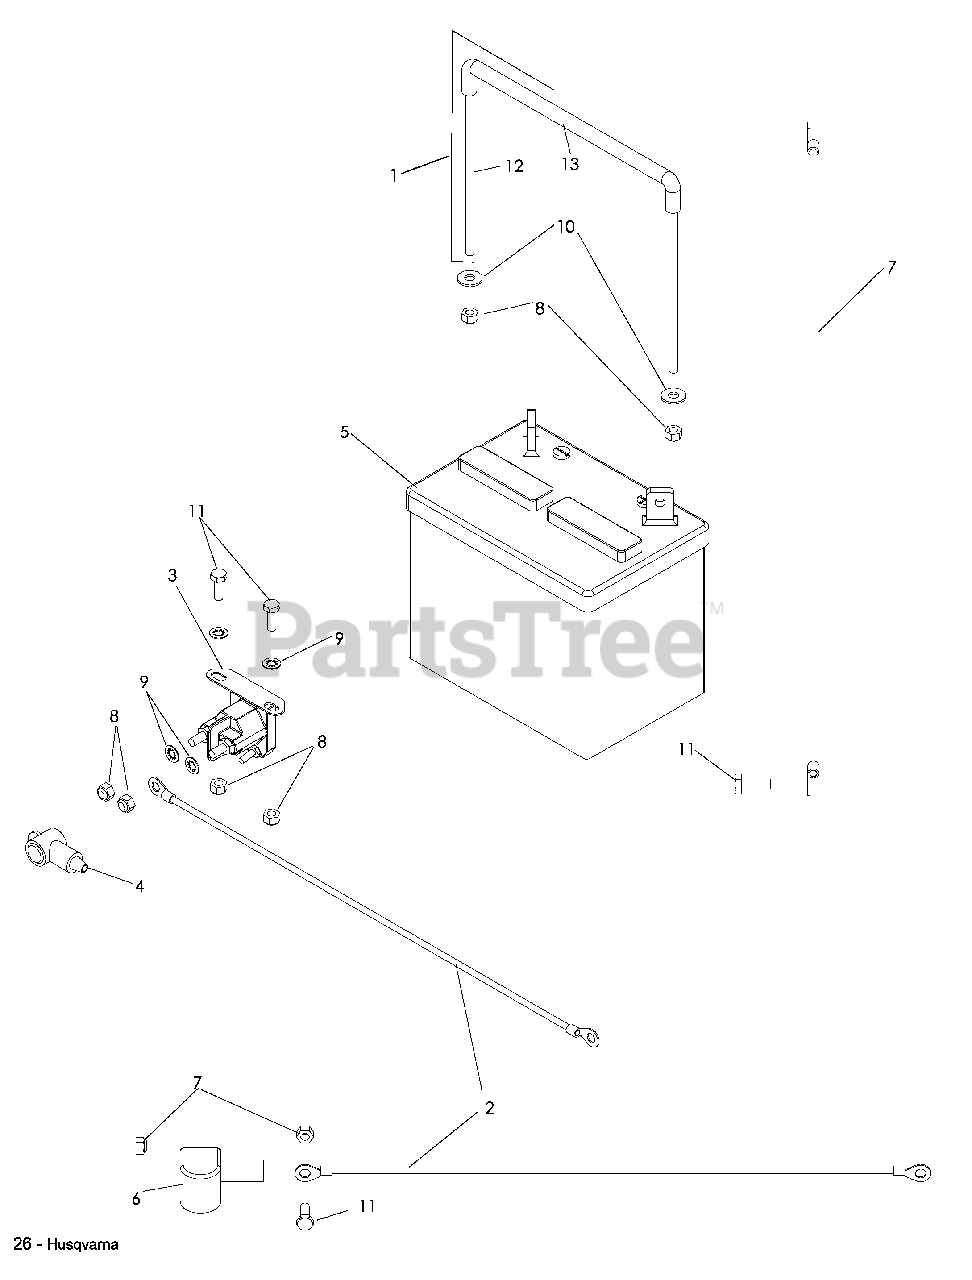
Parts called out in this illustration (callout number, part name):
1	TIEDOWNW/INSULATOR
2	SOLENOID/STARTERCBL
4	TERMINALCOVER-SM
5	BATTERY12V
6	TERMINALCOVER
7	BATTERYCABLE
8	NUT¼-20HEXNYLOC
9	LOCKWASHER¼INT
11	HHB¼-20x¾
12	BATTERYTIEDOWN
13	INSULATOR,TIEDOWN
